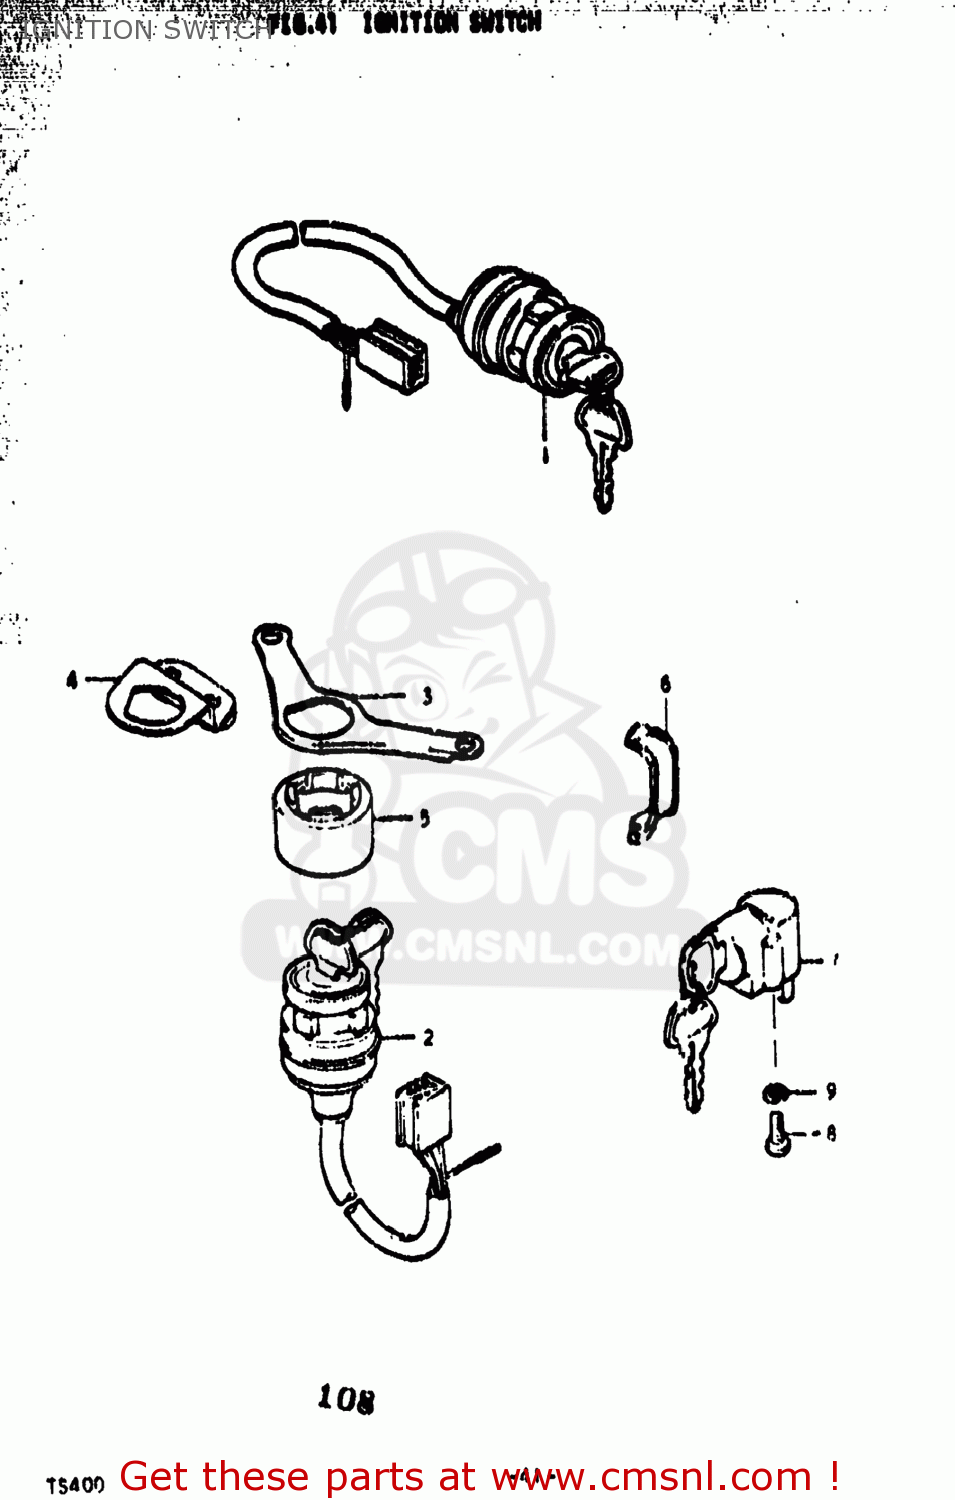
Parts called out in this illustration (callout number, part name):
1	SWITCH ASSEMBLY,IGNITION
2	SWITCH ASSEMBLY,IGNITION
3	BRACKET,IGNITION SWITCH
4	BRACKET,IGNITION SWITCH
5	IGN SWITCH COVE
6	CLAMP
7	LOCK ASSY,STEERING
8	Screw
9	LOCK WASHER
